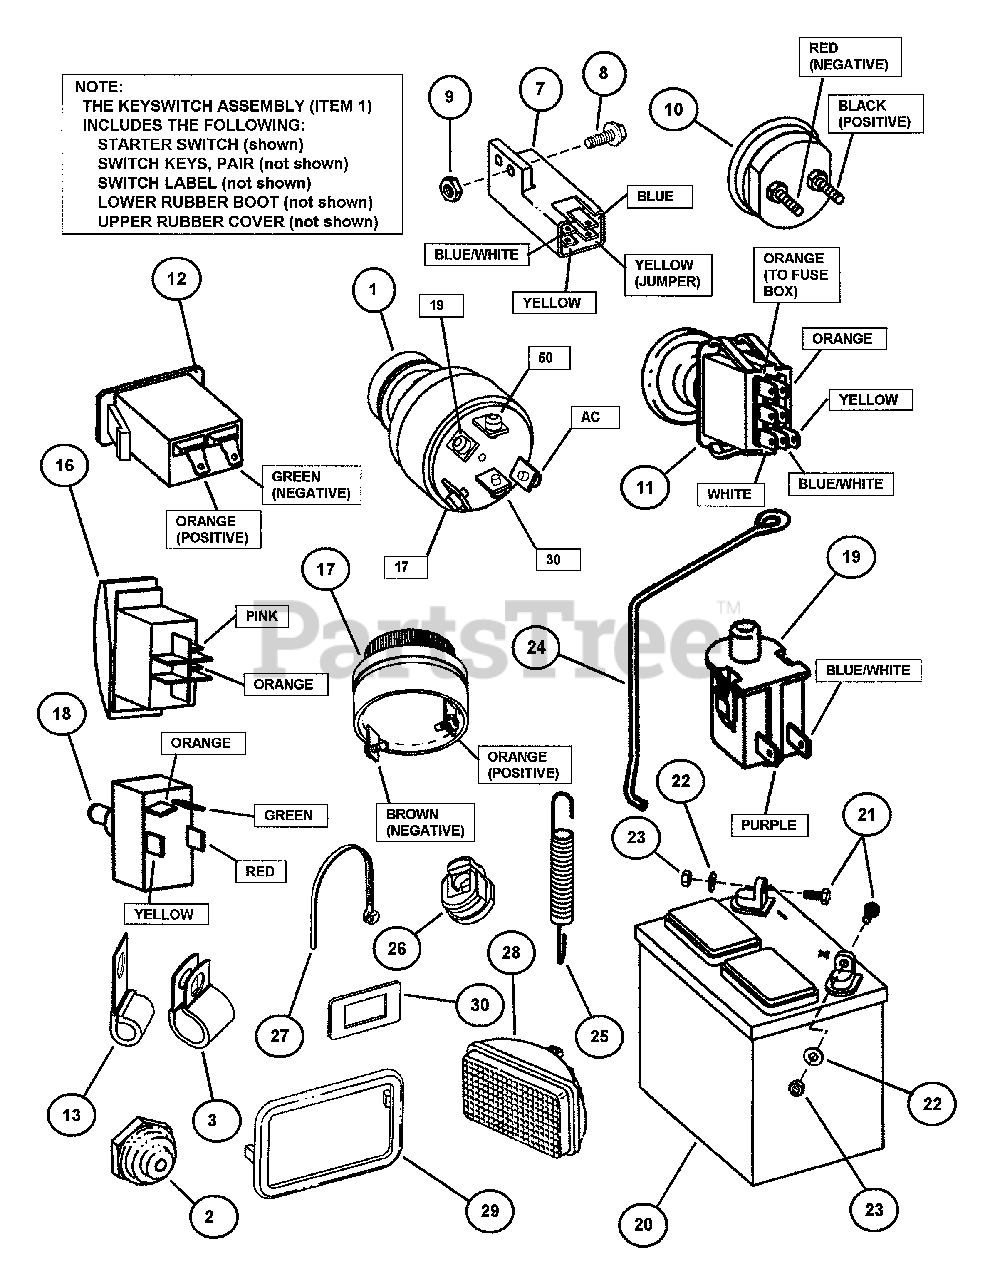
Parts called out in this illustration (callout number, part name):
1	KEYSWITCH, Diesel
2	SEAL, Switch
3	CLIP, Harness
7	SWITCH, DPDT, NO/NO
8	SCREW, #10-32 x 5/8" Hex Wash. Hd. Machine, Grade 5
9	NUT, #10-32 Hex Nyloc
10	ASSEMBLY, Ammeter and Clamp
11	SWITCH, PTO
12	HOUR METER, D.C.
13	CLIP, Open J, 3/8" Cushioned
16	SWITCH, Lights
17	BUZZER, Pulsing
18	SWITCH, Self Centering, Deck Lift
19	SWITCH, Seat
20	BATTERY, 11 Plate-380CCA
21	SCREW, 1/4-20 x 5/8", Hex Head Cap, Grade 5
22	WASHER, .28 I.D. x .63 O.D. x .06 Flat
23	NUT, 1/4-20 Hex Center Lock, Grade 5 or B
24	BRACKET, Battery
25	SPRING, Battery
26	STRAIN RELIEF Wire 2
27	CABLE TIE, 7"
28	HEAD LIGHT
29	BEZEL, Headlight
30	SPACER, PTO Switch
